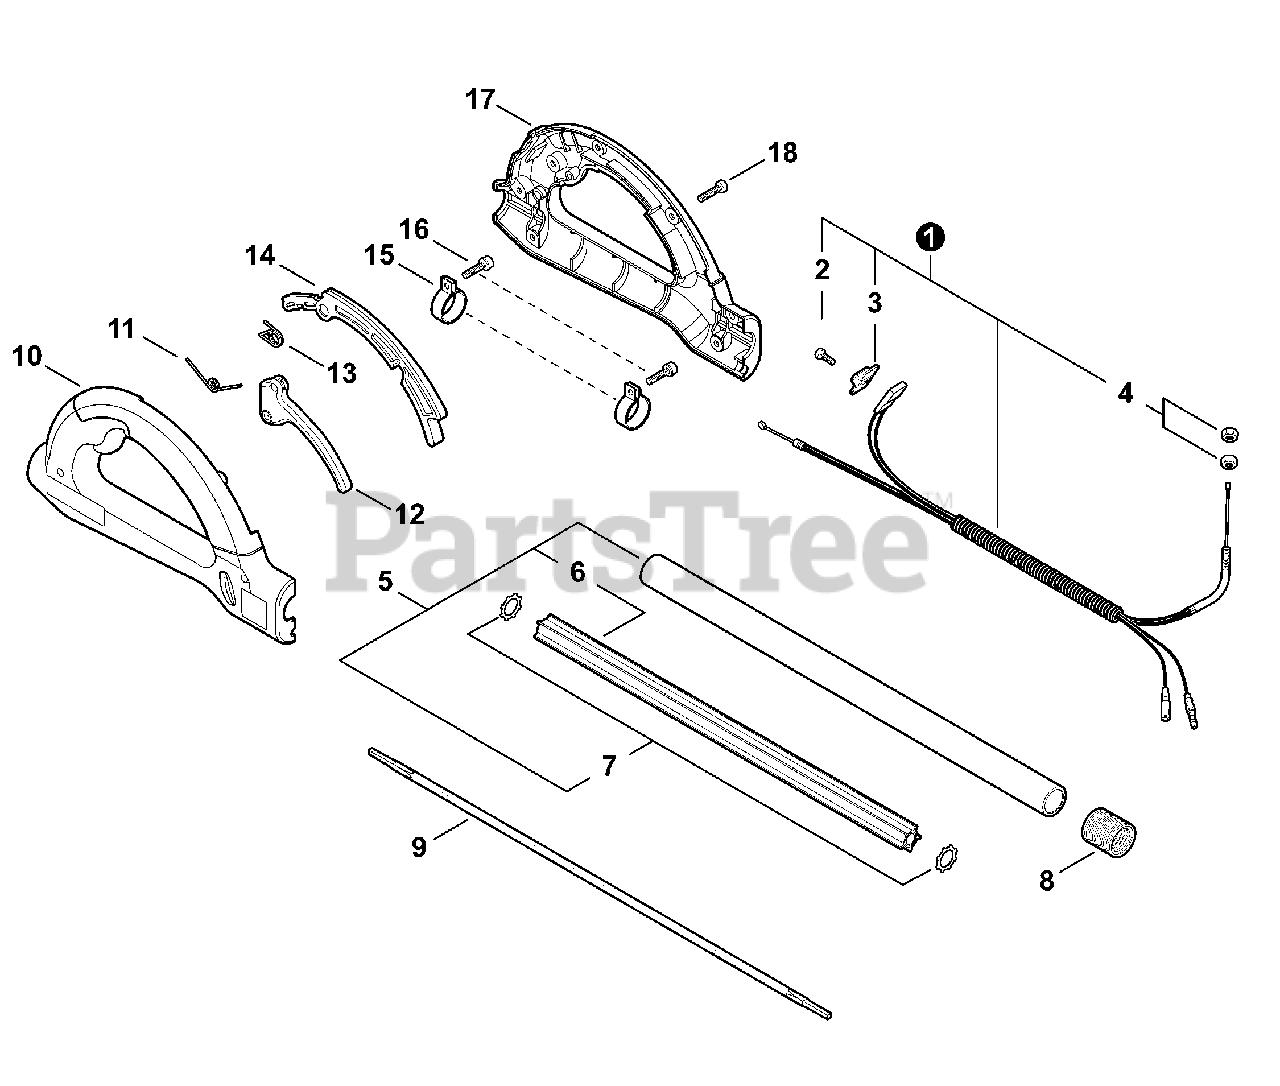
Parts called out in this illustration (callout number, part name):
1	CONTROL CABLE ASSY
2	SCREW - 3×10
3	KNOB, SWITCH - ORANGE
5	PIPE ASY
8	TUBE, PROTECTIVE - CORRUGATED
9	DRIVESHAFT - FLEXIBLE
10	HANDLE - LEFT
11	SPRING, TRIGGER
12	TRIGGER, THROTTLE
13	SPRING, TRIGGER LOCKOUT
14	LOCKOUT, TRIGGER
16	SCREW - 5×20
17	HANDLE - RIGHT
18	SCREW - 5×18
